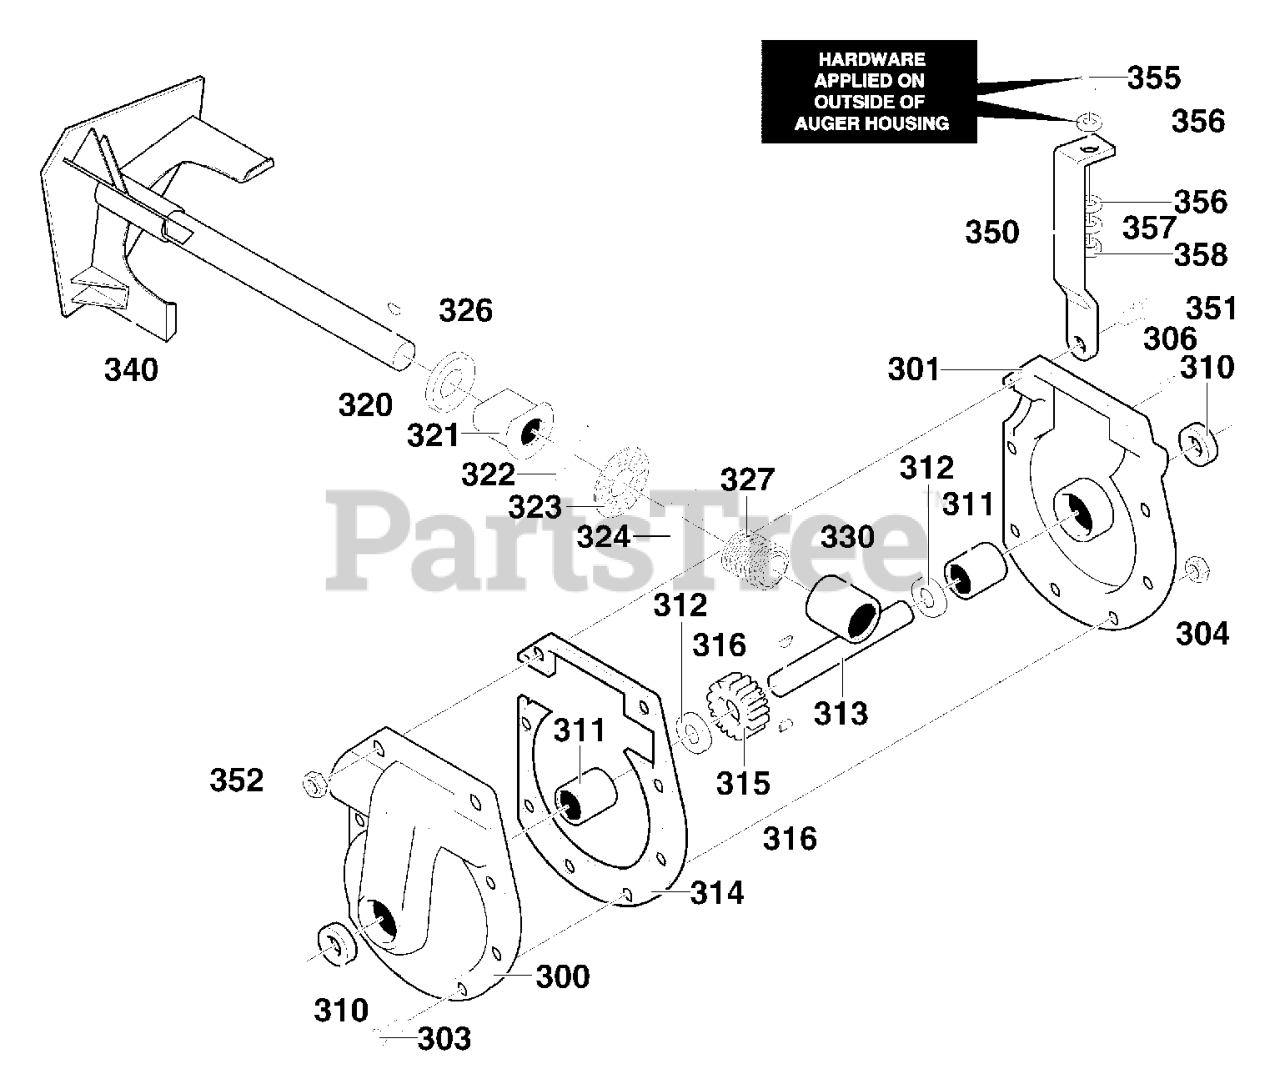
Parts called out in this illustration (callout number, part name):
300	CASE, GEAR, RH
301	CASE, GEAR, LH
303	SCREW, 5/16-24 x 1.00
304	NUT,5/16-24
306	PIPE PLUG
310	SEAL, OIL
311	BEARING, SLEEVE
312	WASHER, FLAT 1.00 x 1.54 x .09
313	SHAFT, AUGER OUTPUT
314	GASKET, GEAR BOX
315	WORM GEAR
316	KEY, WOODRUFF #91
320	RING, QUAD
321	BEARING, FL
322	WASHER, FLAT
323	BEARING, ROLL
324	WASHER, FLAT
327	WORM GEAR
330	BEARING, SLEEVE
350	BRACE, GEAR BOX
351	SCREW 5/16-24X1.75
352	NUT, 5/16-24 HEXWDFLLK
355	SCREW, 5/16-18 x 1.25
356	WASHER, FLAT .349X.69X.066
357	WASHER, SPTLK .31X.58X.08
358	NUT, 5/16-18 REGHEX
